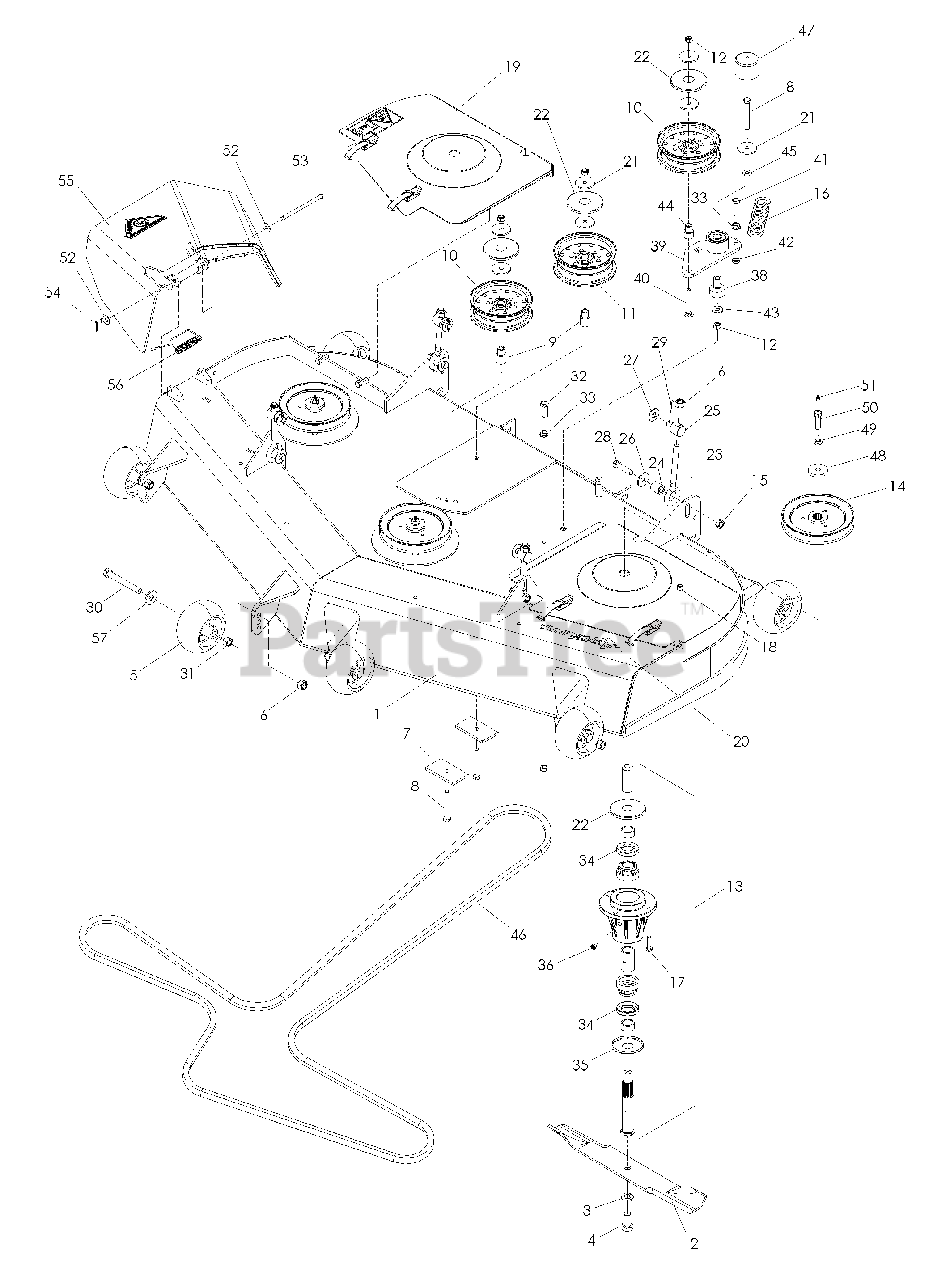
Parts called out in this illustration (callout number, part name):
1	DECK W/DECALS
2	BLADE, 21"
3	WASHER 5/8 SPLIT LOCK
4	HCS 5/8-18 x 1 1/4
5	WHEEL, GAUGE
6	NUT 1/2 -13 HEX NYLOC
7	PAD
8	HCS 3/8-16 x 3
9	BUSHING, IDLER
10	PULLEY, IDLER
11	PULLEY, IDLER
12	NUT 3/8-16 HEX NYLOC
13	HOUSING ASM
15	NUT 7/16-14 HEX CTRLK GR A
17	HCS 5/16-18 x 1 1/4
18	NUT 5/16-18 HEX NYLOC
19	BELT SHIELD w/DECALS, RT
20	BELT SHIELD w/DECALS, LT
20	DECAL, TUNNELRAM
21	WASHER 3/8 SPECIAL
22	DUST CAP, TOP
26	WASHER, SPRING
27	WASHER 9/16 STD FLT
28	HCS 7/16-14 x 1 3/4
29	PIN, COTTER 1/8 x 1
30	HHB 1/2-13 x 4
31	NUT 1/2-13 HEX
32	HCS 3/8-16 x 1 1/4
33	NUT 3/8-16 HEX WHIZLK
34	SEAL, SHAFT
35	DUST CAP, BOTTOM
36	GREASE POPPET
38	BEARING, PIVOT
39	ARM, IDLER W/BEARINGS
40	RHSNB 3/8-16 x 2 3/4
41	HCS 3/8-16 x 1 1/2 GR8
42	NUT 3/8-16 HEX JAM
43	WASHER 3/8 FLAT STD
44	BUSHING, IDLER
45	WASHER 3/8 SAE FLT
46	BELT, DECK
47	CAP, VINYL
48	WASHER, HEAVY
49	LOCKWASHER 7/16
50	HCS 7/16-20 x 1 1/2 GR8
51	ZERK, STRAIGHT 1/4-28
52	WASHER 5/16 STD FLT
53	PIN, CLEVIS 5/16 x 5
54	PIN, COTTER 1/8 x 3/4
55	CHUTE, DISCHARGE
56	SPRING, TORSION
57	WASHER 1/2 FLAT
